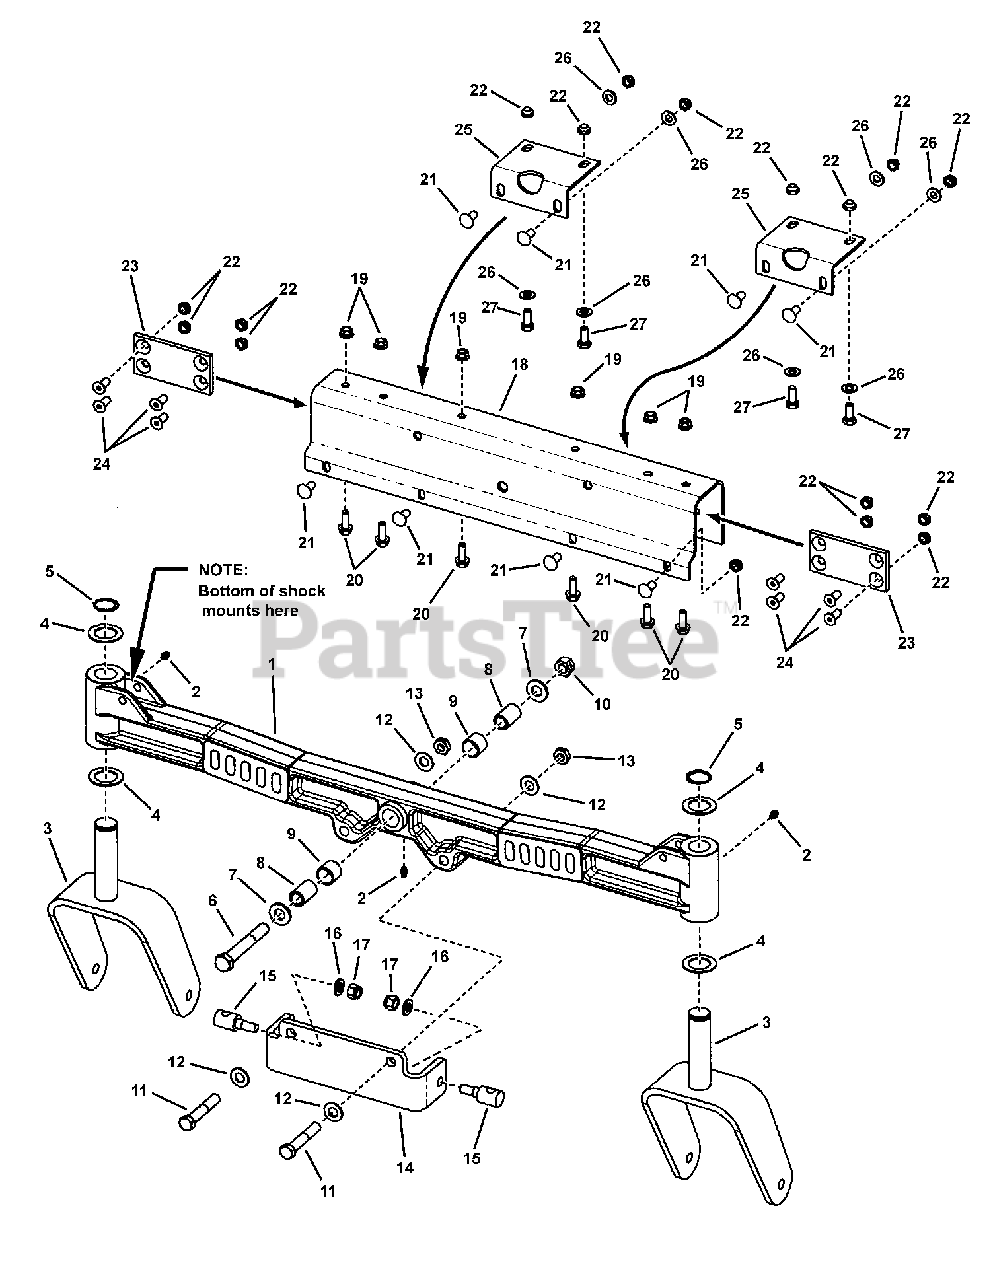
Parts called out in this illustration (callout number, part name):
1	AXLE, Cast, Front, Simplicity Orange
2	LUBE FITTING, 3/16 PR
3	WELD, Caster, Simplicity Orange
4	WASHER, Thrust
5	RETAINING RING, EXT, 1" OD
6	CAPSCREW, Hex Head, 1/2C X3-1/2 YZ
7	WASHER,.531X1.062X.121 ZP
8	SPACER, Axle Pivot
9	BEARING, Sleeve, .875 OD, Powdered Metal
10	NUT, Hex Center Lock, 1/2C GR5 YZ
11	CAPSCREW, Hex Head, 7/16F X2-1/2 GR5 YZ
12	WASHER, .47X.92X.065 YZ
13	NUT, Hex Center Lock Jam, 7/16F GR5 YZ
14	BRACKET, Quick Hitch
15	SWIVEL, 3/8, Yellow
16	WASHER, .406X1.25X.132 ZP
17	NUT, Hex, 3/8C, Nylock YZ
18	BRACKET, AXLE, Simplicity Orange
19	NUT, Hex Flange Lock, 5/16C GR5 YZ
20	CAPSCREW, Hex Head, Whiz Lock, Flange, 5/16C X7/8 YZ
21	CARRAIGE BOLT, 5/16C X3/4 GR5 YZ
22	NUT, Hex, Lock, Taptite, 5/16C
23	PLATE, Friction
24	FHHR, 5/16C X 1
25	BRACKET, Axle Support
26	WASHER, .34X.69X.08 YZ
27	CAPSCREW, Hex Head, 5/16C X3/4 GR5 YZ
